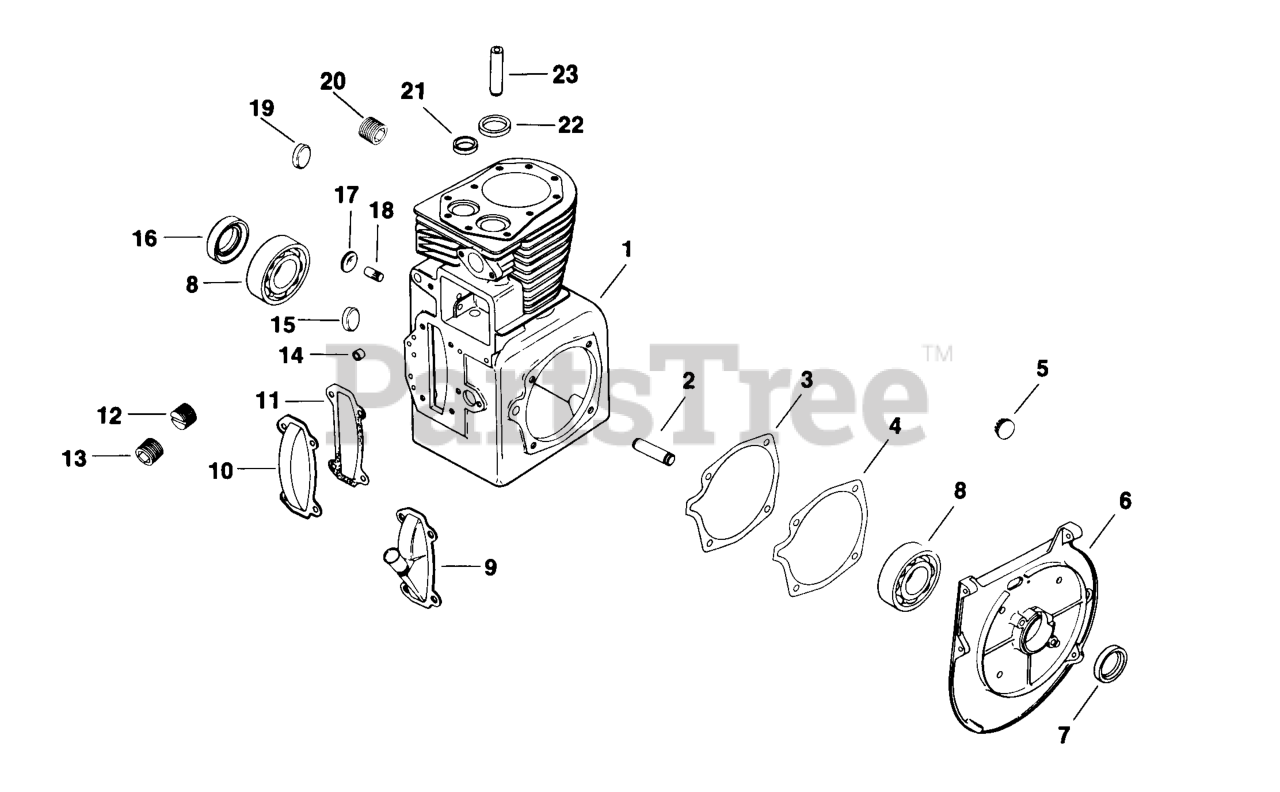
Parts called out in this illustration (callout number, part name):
1	Cylinder block
3	GASKET, BEARING PLATE
4	GASKET, BEARING PLATE
6	PLATE
7	SEAL, FRONT OIL
8	BEARING, BALL
10	COVER, CAMSHAFT - DISCONTINUED
11	GASKET, CAMSHAFT COVER
14	BEARING
15	PLUG, CUP 1/2" USE 25 139 50-S
16	SEAL, REAR OIL
17	PLUG, WELCH EXPANSION
18	SHAFT, GOVERNOR GEAR
20	PLUG - DISCONTINUED
21	INSERT - DISCONTINUED
23	GUIDE, VALVE - DISCONTINUED
